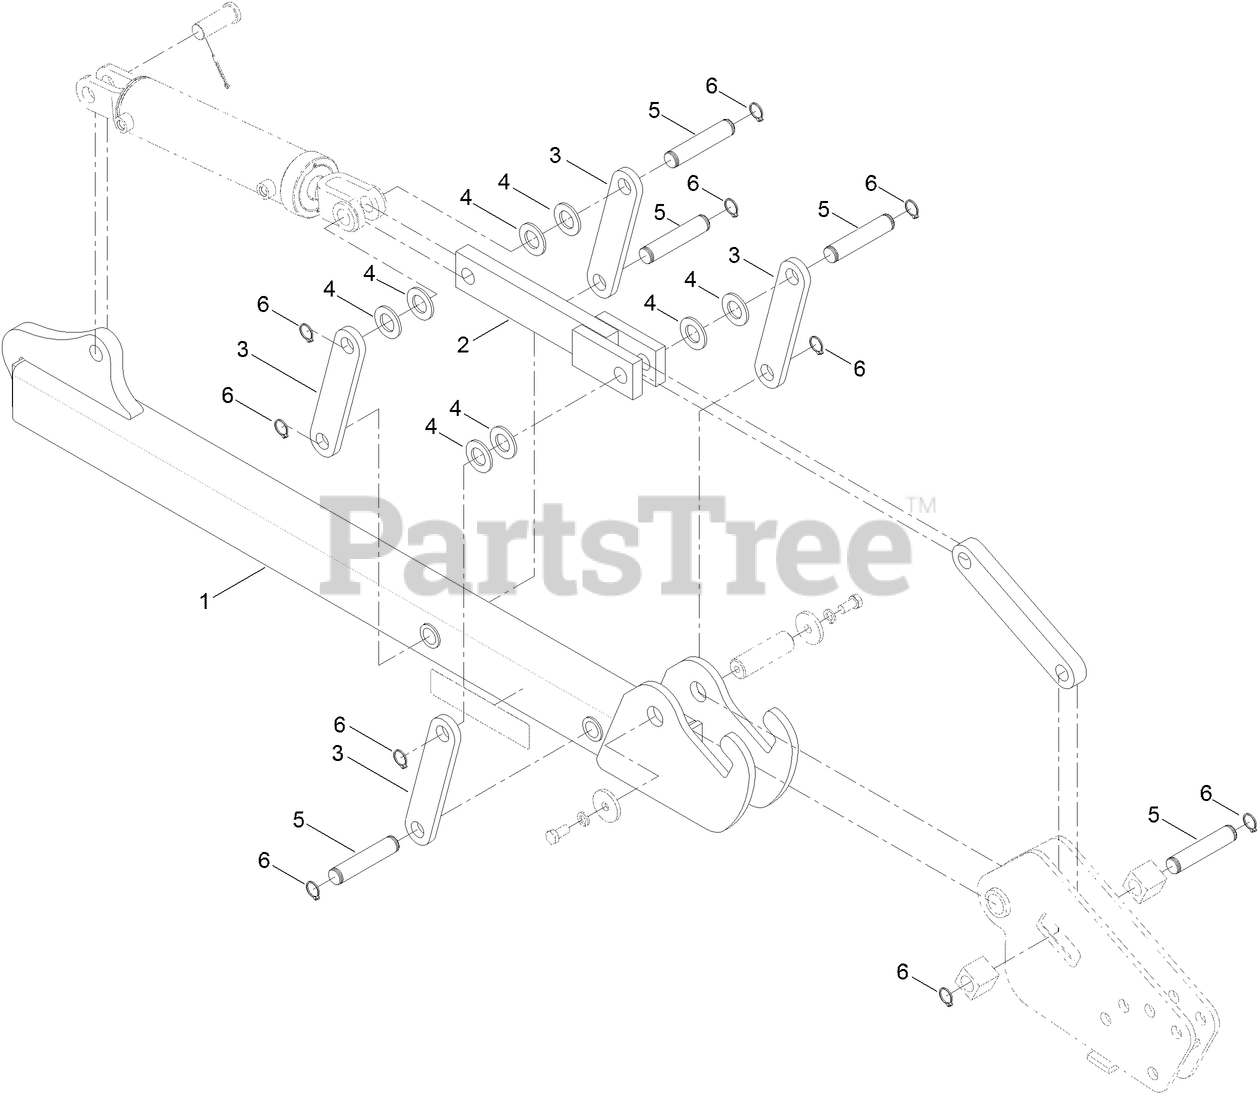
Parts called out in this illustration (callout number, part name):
1	TUBE-CRUMBER, 6 FT
2	EXTENSION-BAR
3	LINK-CRUMBER, STRAIGHT
5	PIN-CYLINDER, ROD
6	RING-RETAINING
